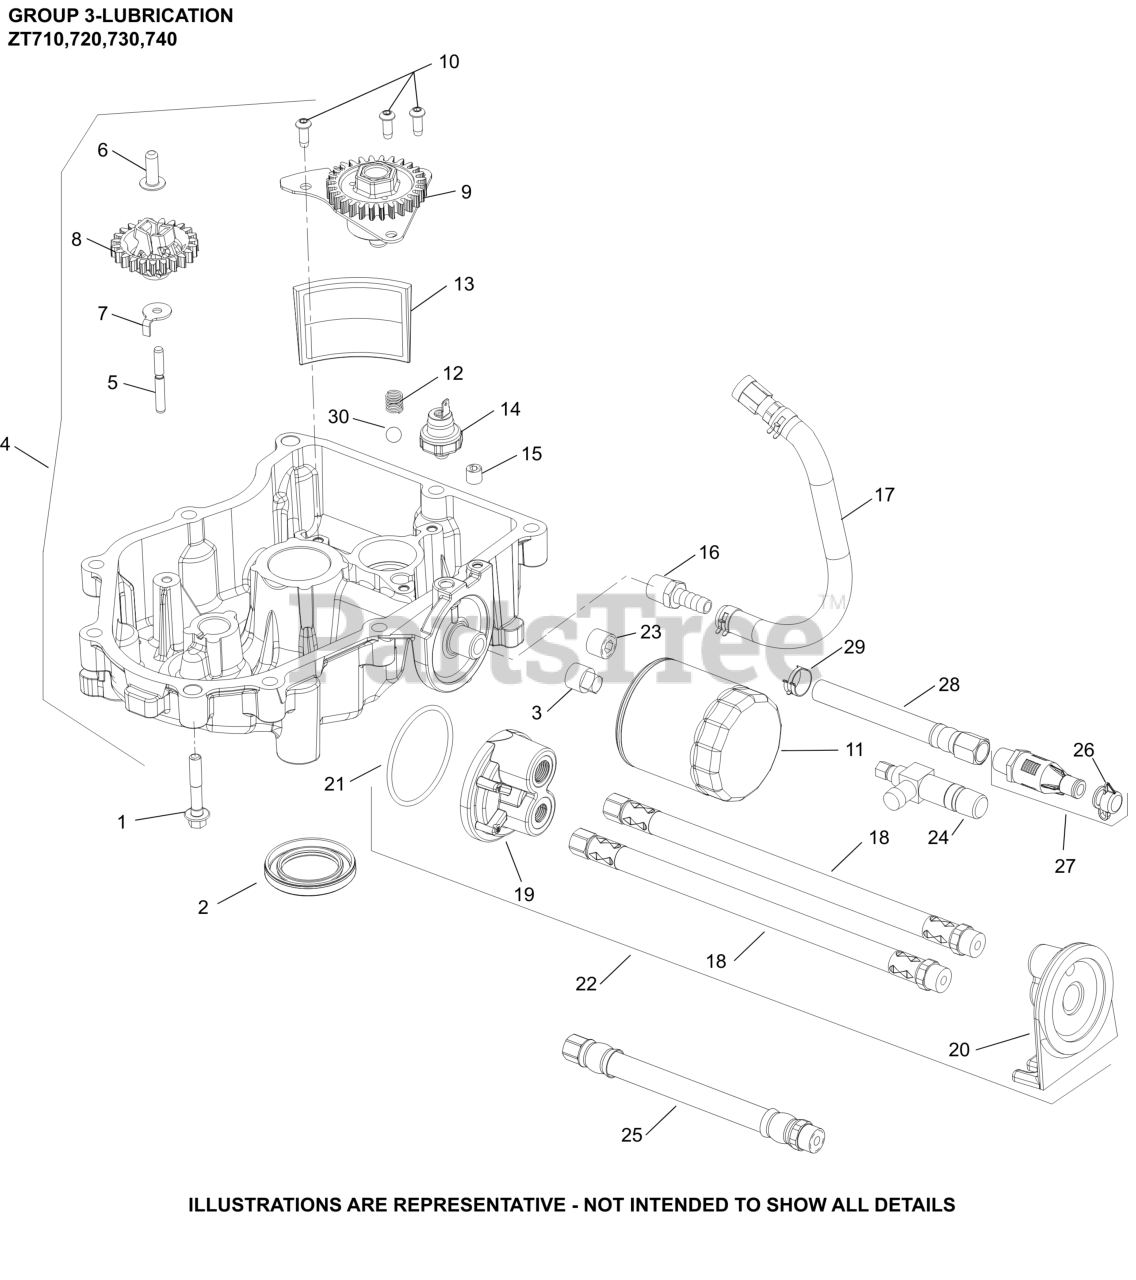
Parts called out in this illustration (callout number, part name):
1	SCREW, FLG M8X1.25X45
3	PLUG, SQ HD PIPE 3/8"
4	OIL PAN ASM (SLEEVE BEARING) (SERVICE)
6	PIN, GOVERNOR REGULATING
7	TAB, LOCKING
8	KIT, GOVERNOR GEAR
10	SCREW, BUTTON HEAD
12	SPRING, COMPRESSION
13	SCREEN, OIL
14	SENSOR, OIL PSI
24	VALVE, OIL DRAIN MEDIUM
30	PRESSURE RELIEF BALL
NI	FILTER, OIL EXTENDED LIFE
NI	SHAFT, GOVERNOR GEAR
